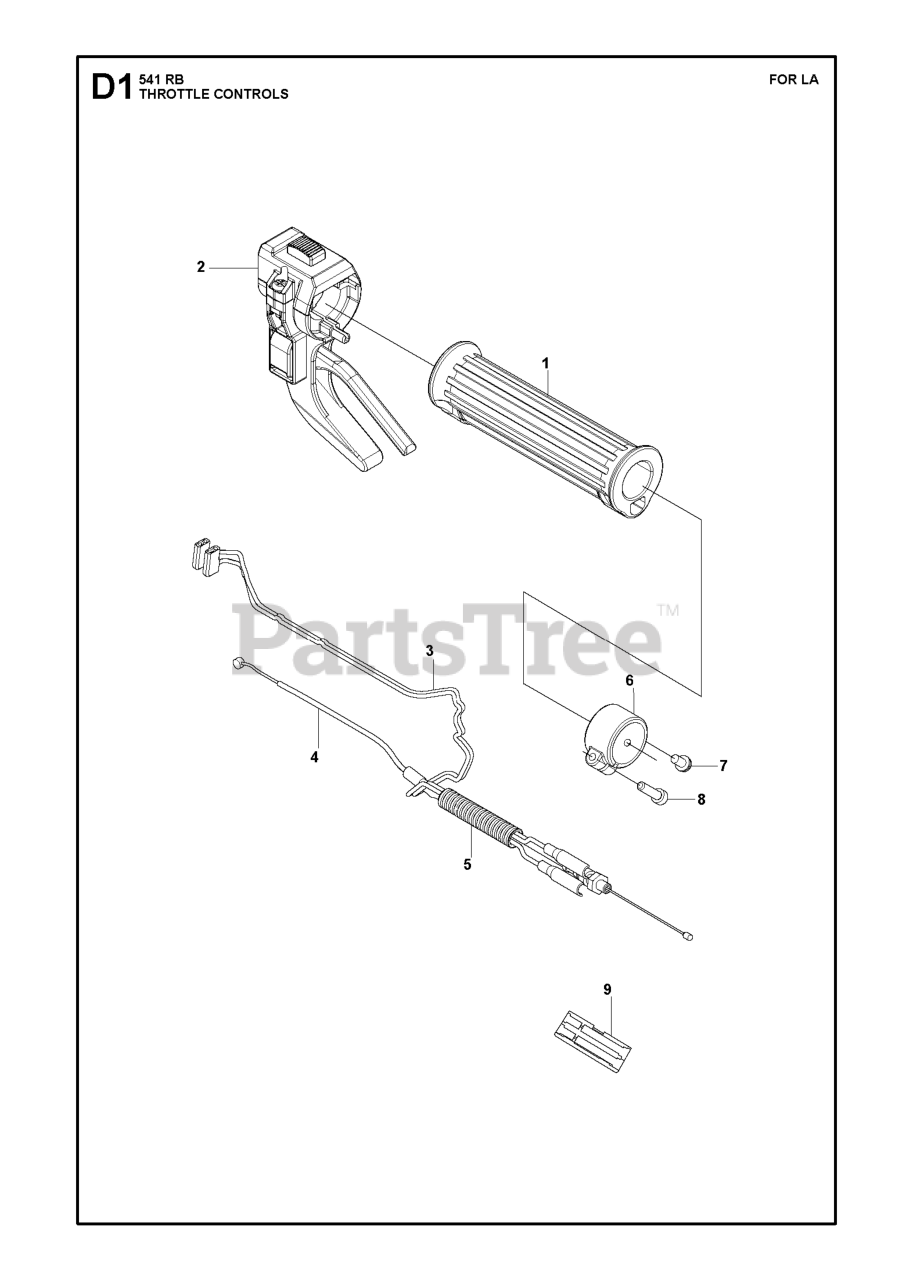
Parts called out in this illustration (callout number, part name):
6	CLAMP
7	BOLT
8	BOLT TORX
